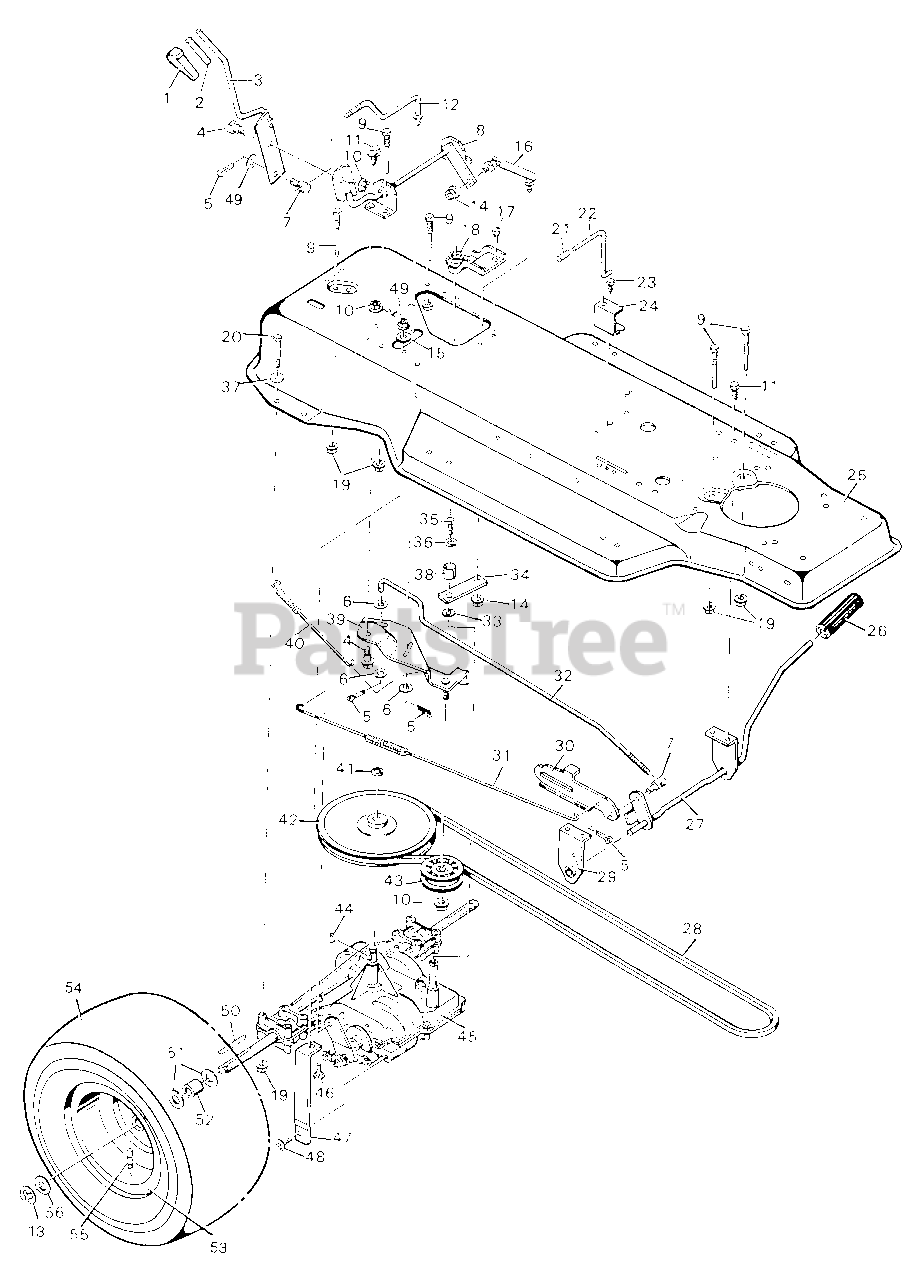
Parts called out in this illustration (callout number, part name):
2	GRIP- Inner
3	HANDLE- Shift
4	BOLT- Shoulder
5	PIN- Cotter
6	WASHER
7	NUT- Adjustable
8	SHIFTER ASSEMBLY
9	GUIDE- Belt
10	NUT- Lock (flange)
12	LINK- Clutch
14	NUT- Lock (flange)
16	SHIFTER LINK ASSEMBLY
18	BRACKET- Support
19	NUT- Flange
20	BOLT- Hex
22	ROD- Control
24	GUIDE- Bracket
26	CLUTCH AND BRAKE PEDAL
27	LEVER ASSEMBLY
28	BELT- Motion drive
29	BRACKET- Support
30	LATCH- Park brake
31	SPRING- Brake extension
32	ROD- Clutch
34	YOKE- Shift
35	BOLT- Hex
36	WASHER- Lock
38	PILOT- Support
39	BRACKET ASSEMBLY- Idler
40	SPRING- Motion drive extension
41	RING- Retainer
42	PULLEY- Motion drive
43	PULLEY- Backside idler
44	KEY- Woodruff #9
46	BOLT- Carriage
47	SUPPORT- Transaxle
49	WASHER
50	KEY- Square
52	SPACER- Transaxle
53	WHEEL & TIRE ASSEMBLY
55	STEM-Valve
